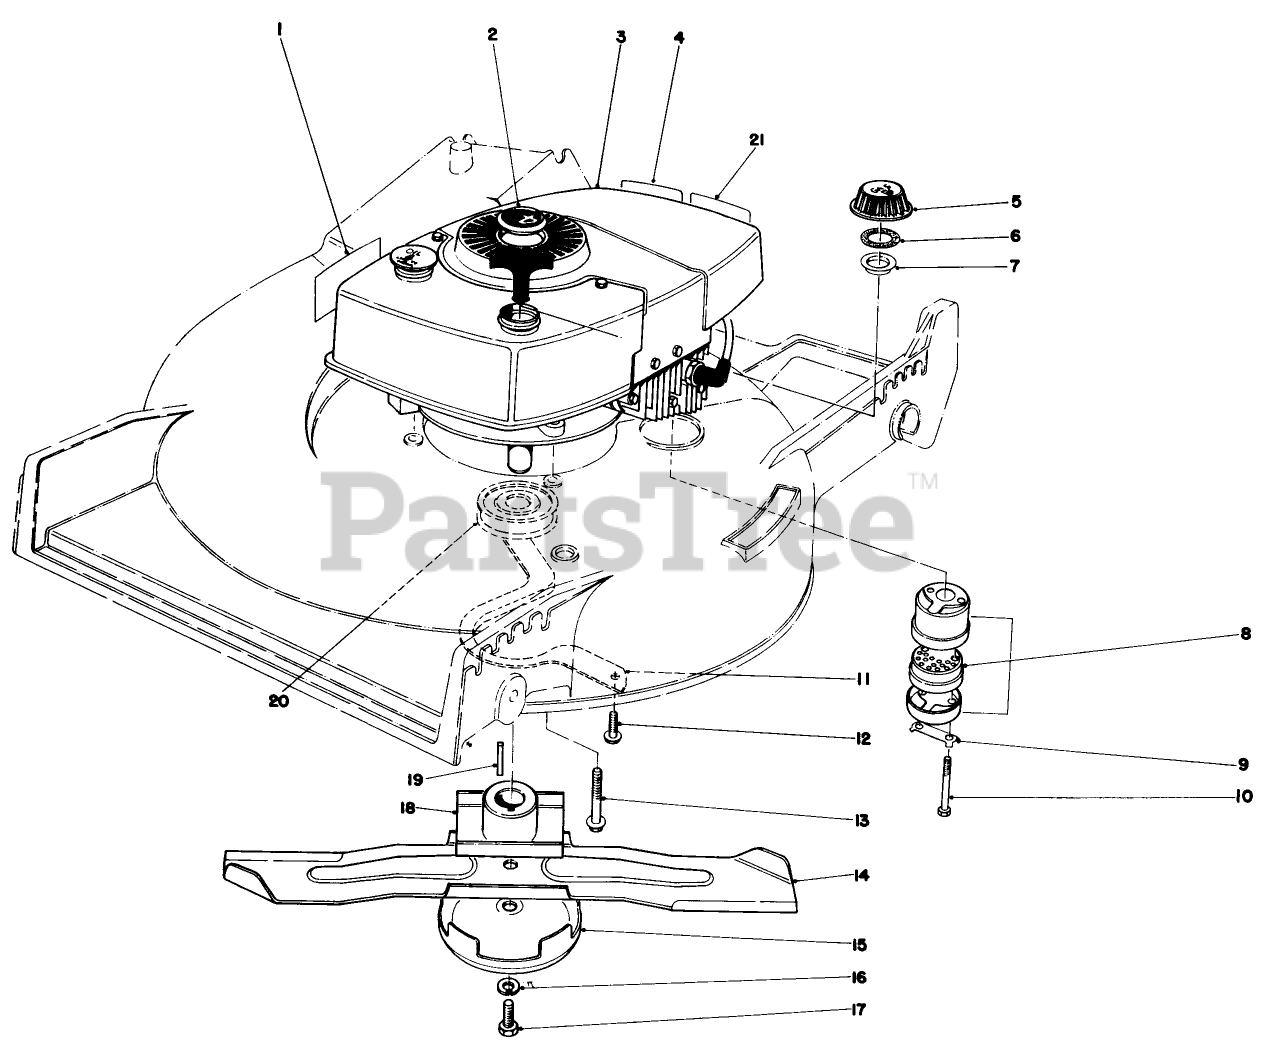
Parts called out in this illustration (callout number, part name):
1	Decal Toro
2	Plug Button
3	Engine
4	Decal-Maintenan
5	Gas Cap (Incl. Ref. #6 & 7)
6	GASKET
7	GAS CAP BAFFLE
8	Muffler Assembly (Incl. Ref. #9 & 10)
9	CLIP - LOCKING
10	SCREW-HH
11	BELT GUIDE
12	Screw
13	SCREW-HWHTF
14	Blade
15	AntiScalp Cup
16	WASHER-LOCK
17	BLADE SCREW
18	BLADE RETAINER WA(BLACK)
19	KEY-SQUARE
20	DRIVER PULLEY
21	Decal Maintenance
